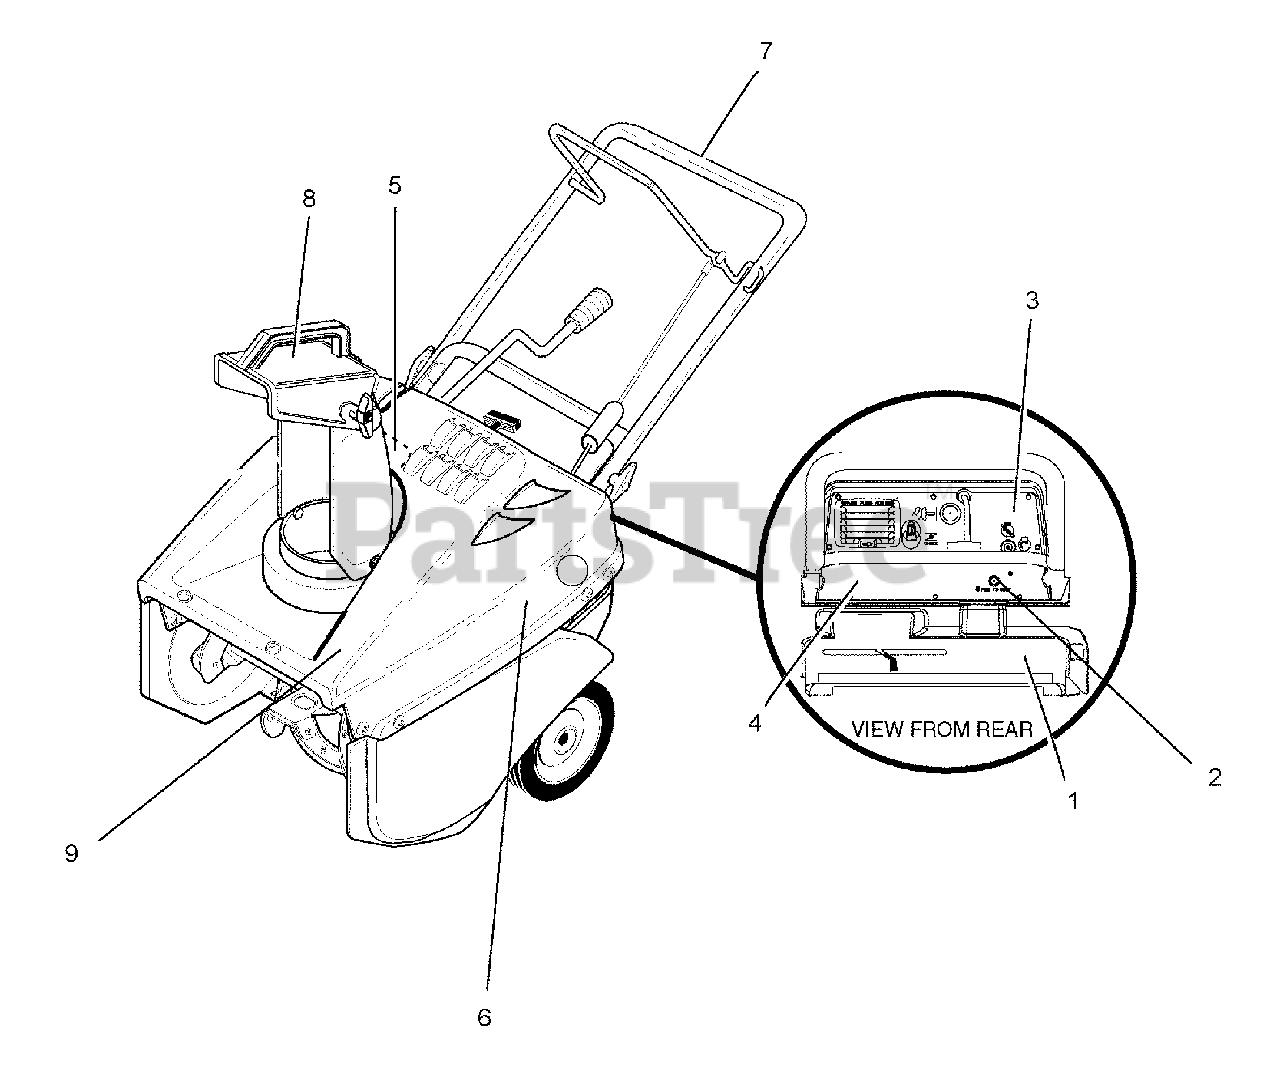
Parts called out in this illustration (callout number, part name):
1	DECAL, EPA, MASS
2	DECAL, ELECTRIC START, COVER UP
2	DECAL, ELECTRIC START
3	DECAL, DASH PANEL
4	DECAL, HUSQVARNA
5	DECAL, HUSQVARNA 5021R
5	DECAL, HUSQVARNA 5021E
6	DECAL, WARNING HOT MUFFLER
7	DECAL, AUGER CONTROL
8	DECAL, DANGER CHUTE
9	DECAL, DANGER AUGER, FOOT
